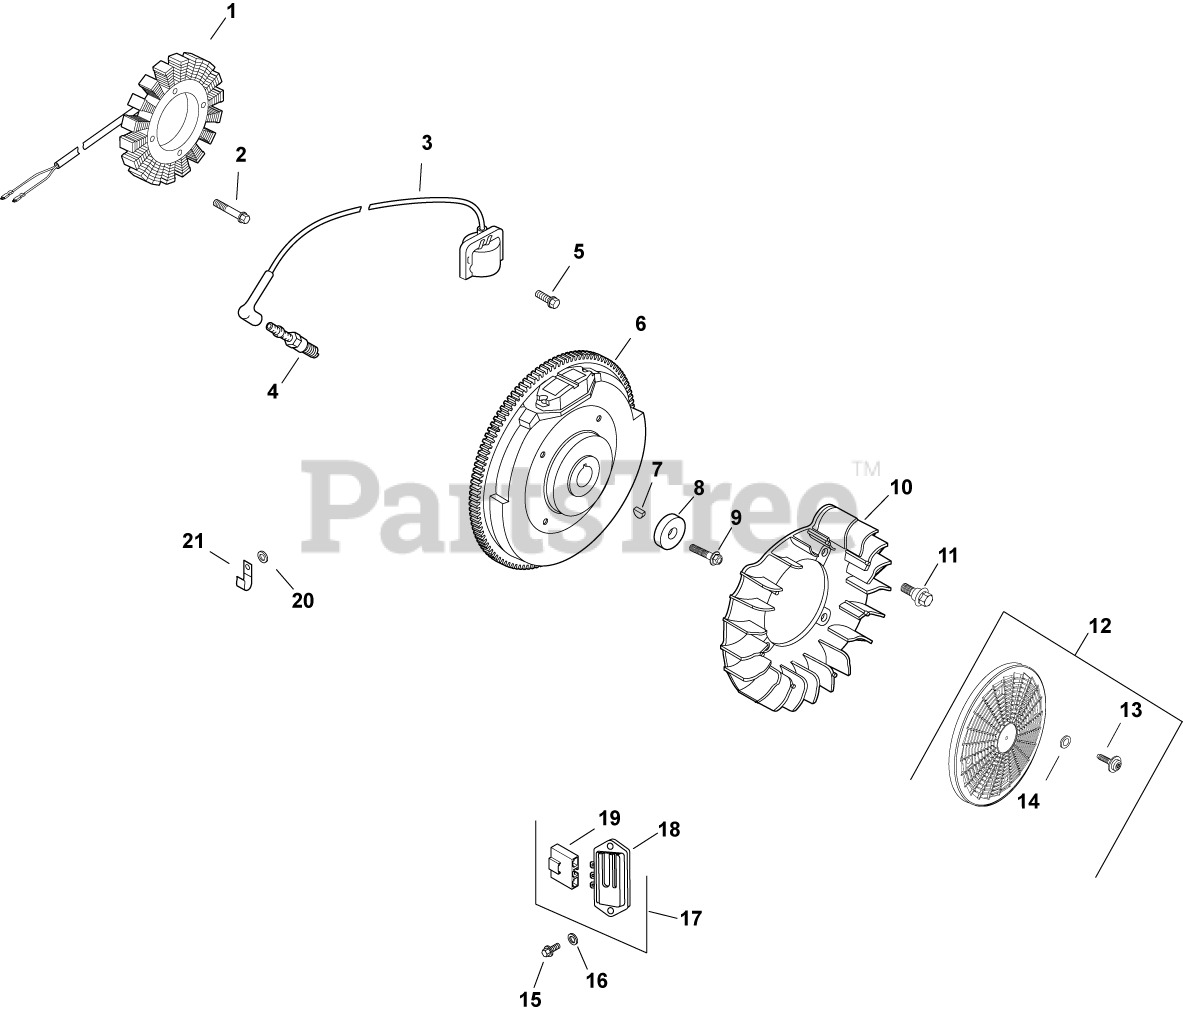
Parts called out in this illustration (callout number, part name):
1	KIT, 25 AMP STATOR ASSY.
2	SCREW, THD FROM M5X0.8X30
3	MODULE, IGNITION-USE 24 584 45-S
4	PLUG, SPARK (STD)
5	SCREW, FLG THD FRM M5X.8X20-(#25086399S)
6	FLYWHEEL, PAINTED-USE 24 025 59-S
7	KEY, 3/16" X 5/8"
8	WASHER, FLAT 13/32"
9	SCREW, FLG M10X1.5X45 - (#25086361S)
10	FAN USE 24 755 253-S
11	BOLT, SHOULDER
12	KIT, GRASS SCREEN
13	SCREW, FLG SEMS M4X.7X25
14	WASHER, FLAT 3/16"
15	SCREW, PHL HD #11-16X7/8"
16	WASHER, FLAT 7/32"
17	KIT, FULL WAVE CONVERSION
18	REG/RECTIFIER (20/25 AMP)-USE 25 403 20-
19	CONNECTOR, BODY (KM)-USE 25 155 41-S
20	WASHER, FLAT 1/4" (O.D. 1/2")
21	CLIP, CABLE
